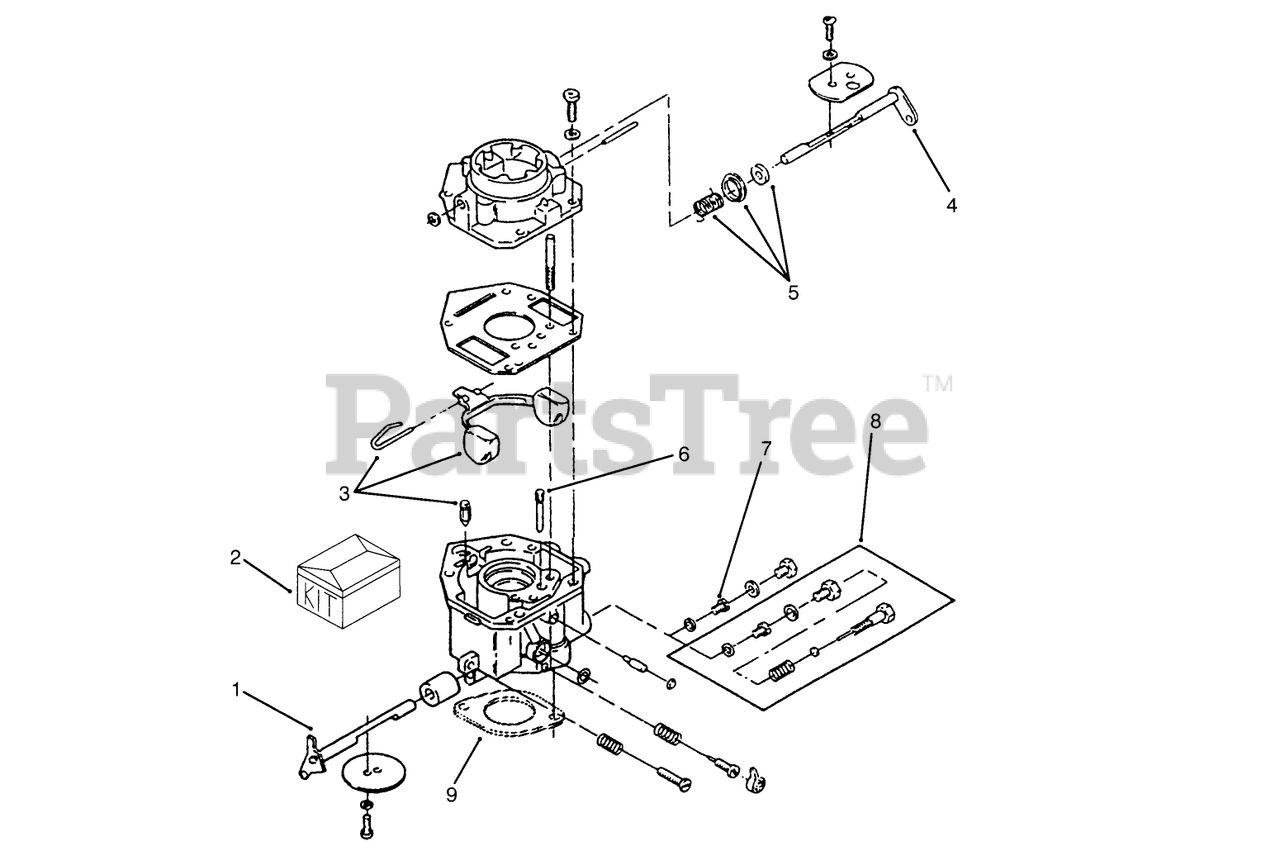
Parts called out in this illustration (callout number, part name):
2	REPAIR KIT
3	FLOAT
4	CHOKE KIT SHAFT
6	IDLE-JET
8	FIXED-JET
9	GASKET-CARBURETOR
